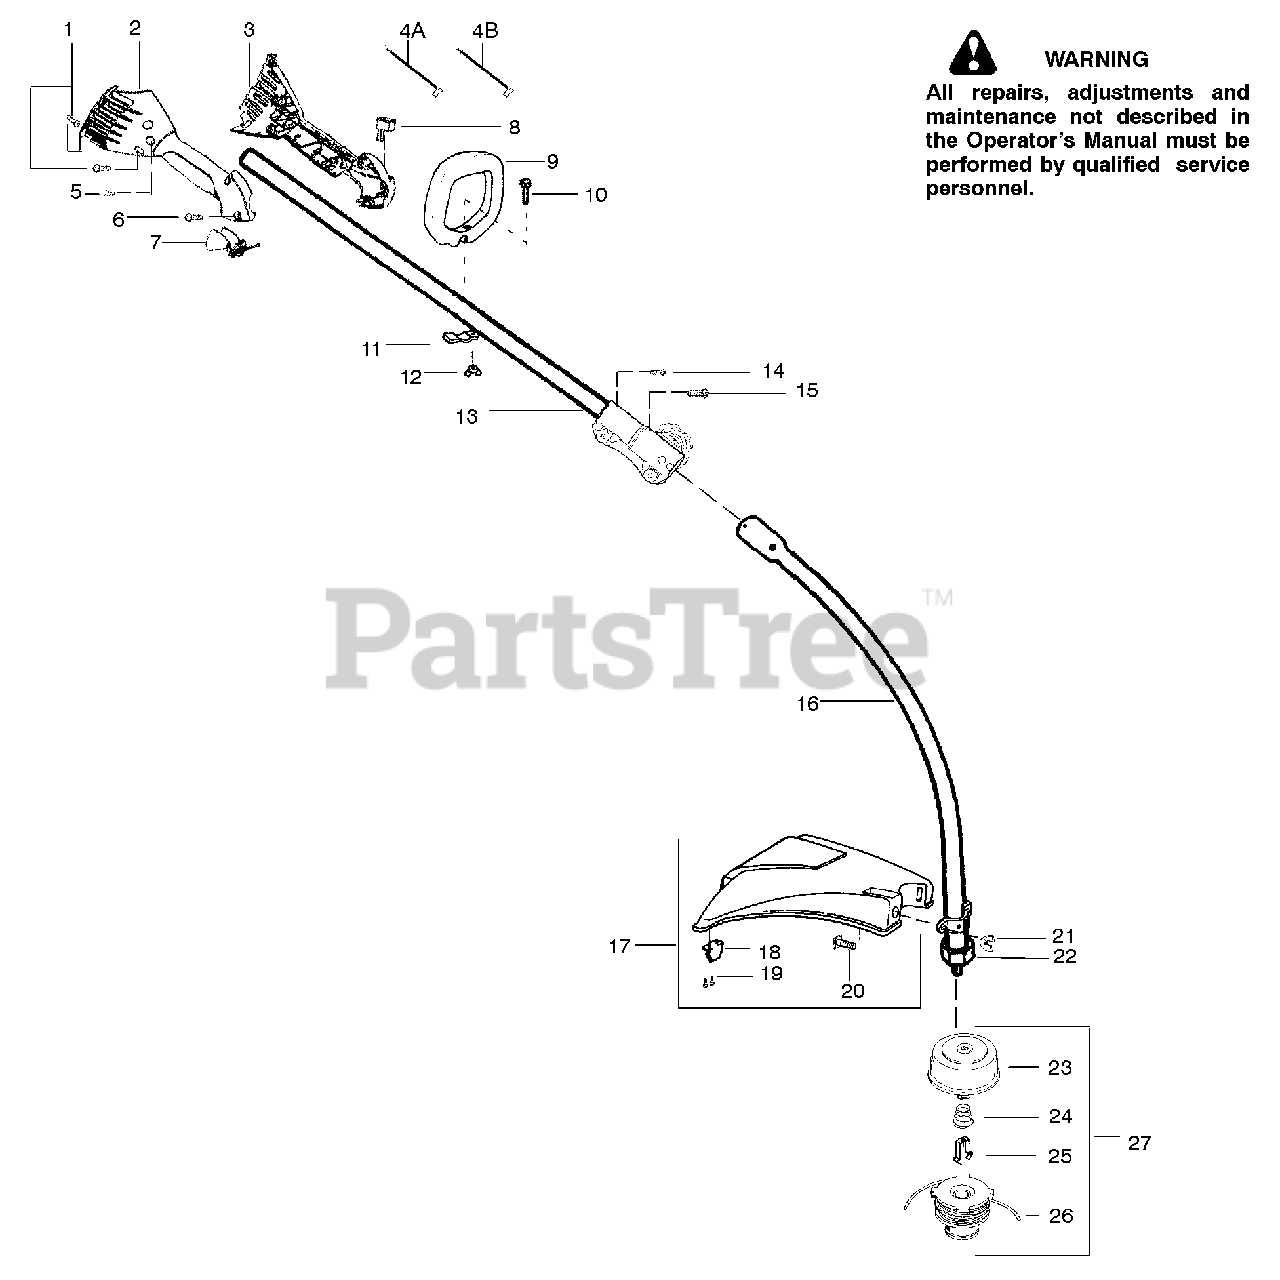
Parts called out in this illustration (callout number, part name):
1	Screw-handle/fan hsg
2	Throttle Hsg. (Right)
3	Kit-Left Throttle Hsg.
4A	Assy-Front Wire Lower Front Wire
4B	Assy-Front Wire Upper Front Wire
5	Screw-Alignment
8	Kit-Switch
9	Assy-Assist Handle
11	Clamp-Assist Handle
12	Wingnut
13	Assy-Upper Shaft
14	Screw-Alignment
16	Assy-Lower Shaft
17	Kit-Shield Ass'y.
18	Line Limiter
19	Screw-Line Limiter
21	Wingnut
23	Assy-Hub/Arbor
24	Spring-Return
25	Retainer-Spool
26	Accy-Wound Spool
27	Assy-TNG VI 3/8" -RH 2x
